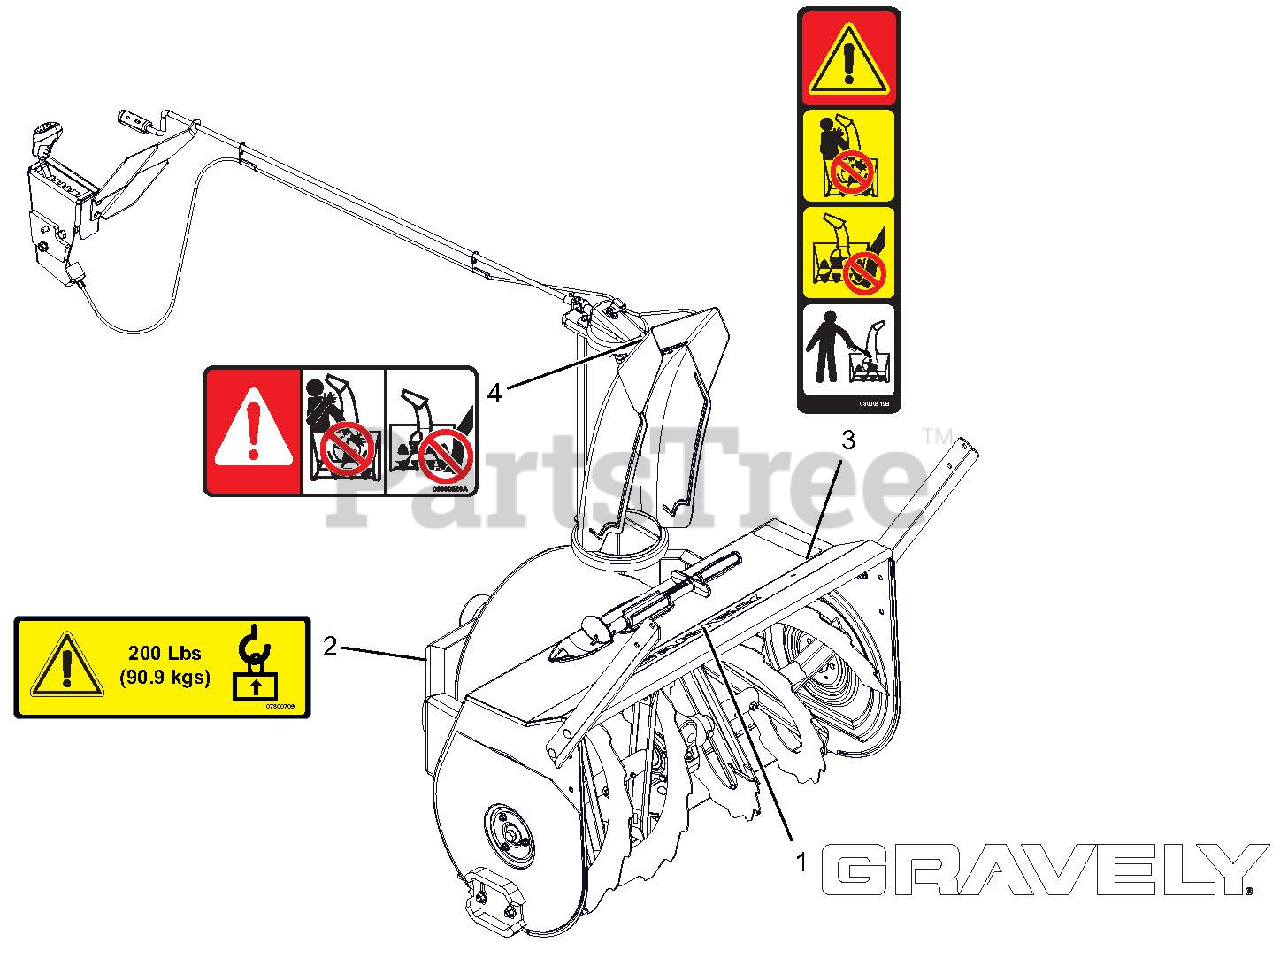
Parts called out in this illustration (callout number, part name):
1	DECAL, 13.5" GRAVELY LOGO
2	DECAL, 32" SNOWHEAD WEIGHT
3	DECAL, DANGER - ROTATING PARTS
4	DECAL, DANGER
